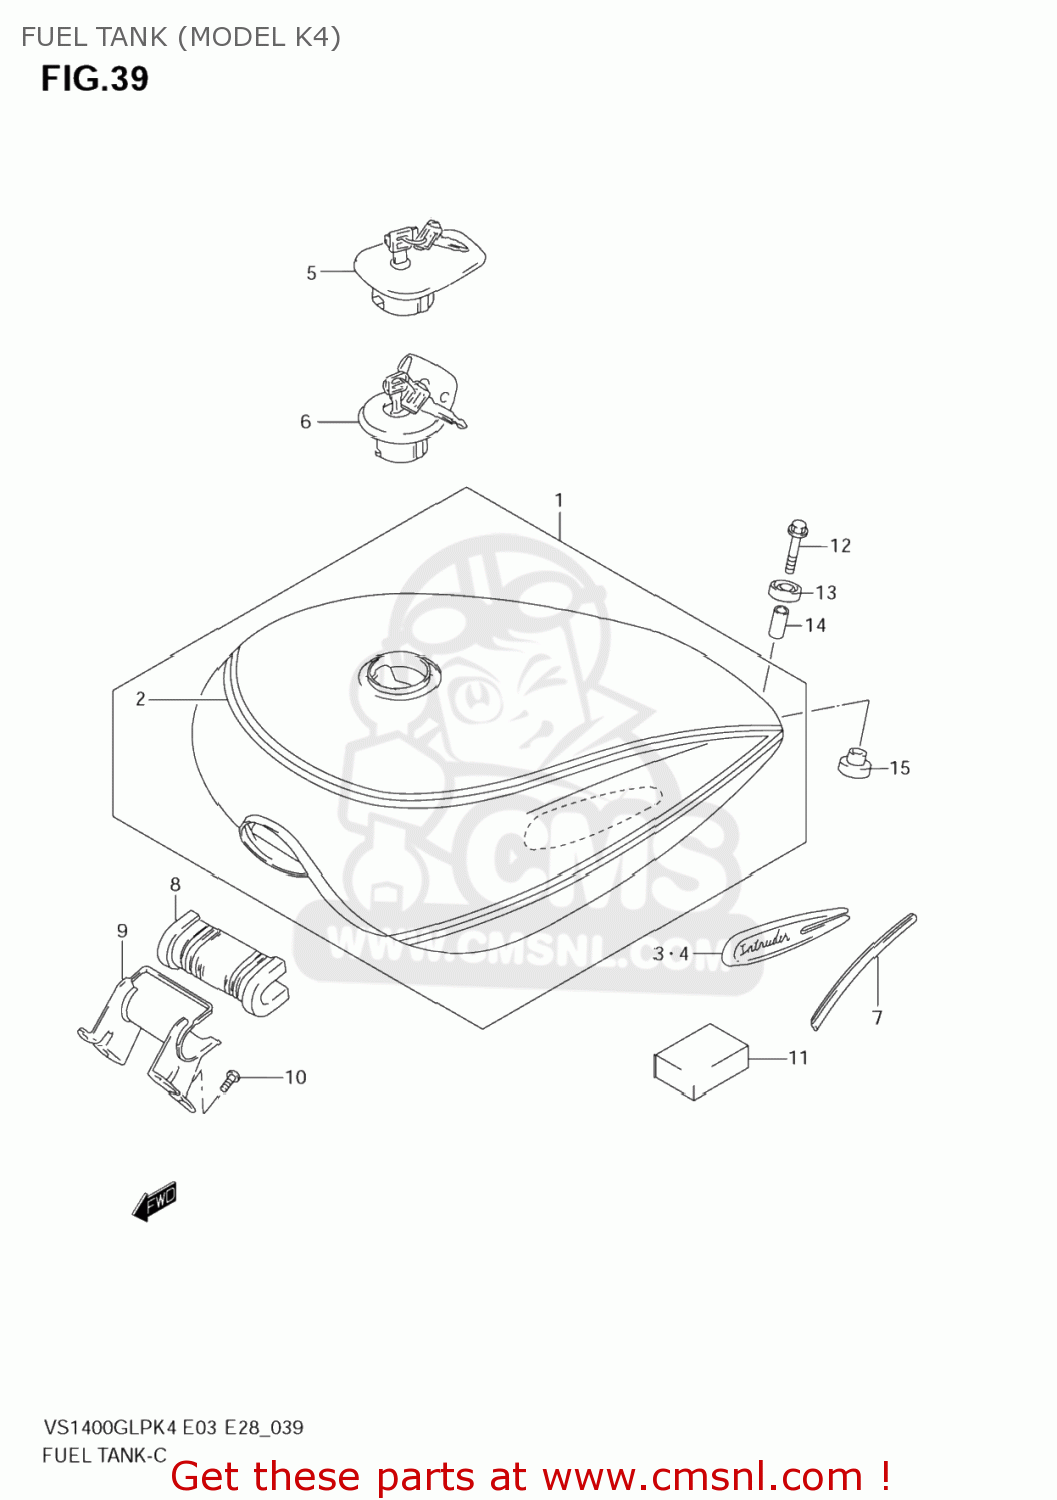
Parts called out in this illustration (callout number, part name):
1	TANK ASSY,FUEL
2	TAPE SET,FUEL TANK STRIPE
3	EMBLEM,FUEL TANK,R
4	EMBLEM,FUEL TANK,L
5	CAP SET,FUEL TANK
6	CAP SET,FUEL TANK
7	MOLDING
8	CUSHION,FUEL TANK FR
9	BRACKET,FUEL TANK FR
10	SCREW
11	CUSHION
12	BOLT
13	CUSHION
14	SPACER(6.5X9X22.5)
15	CUSHION
